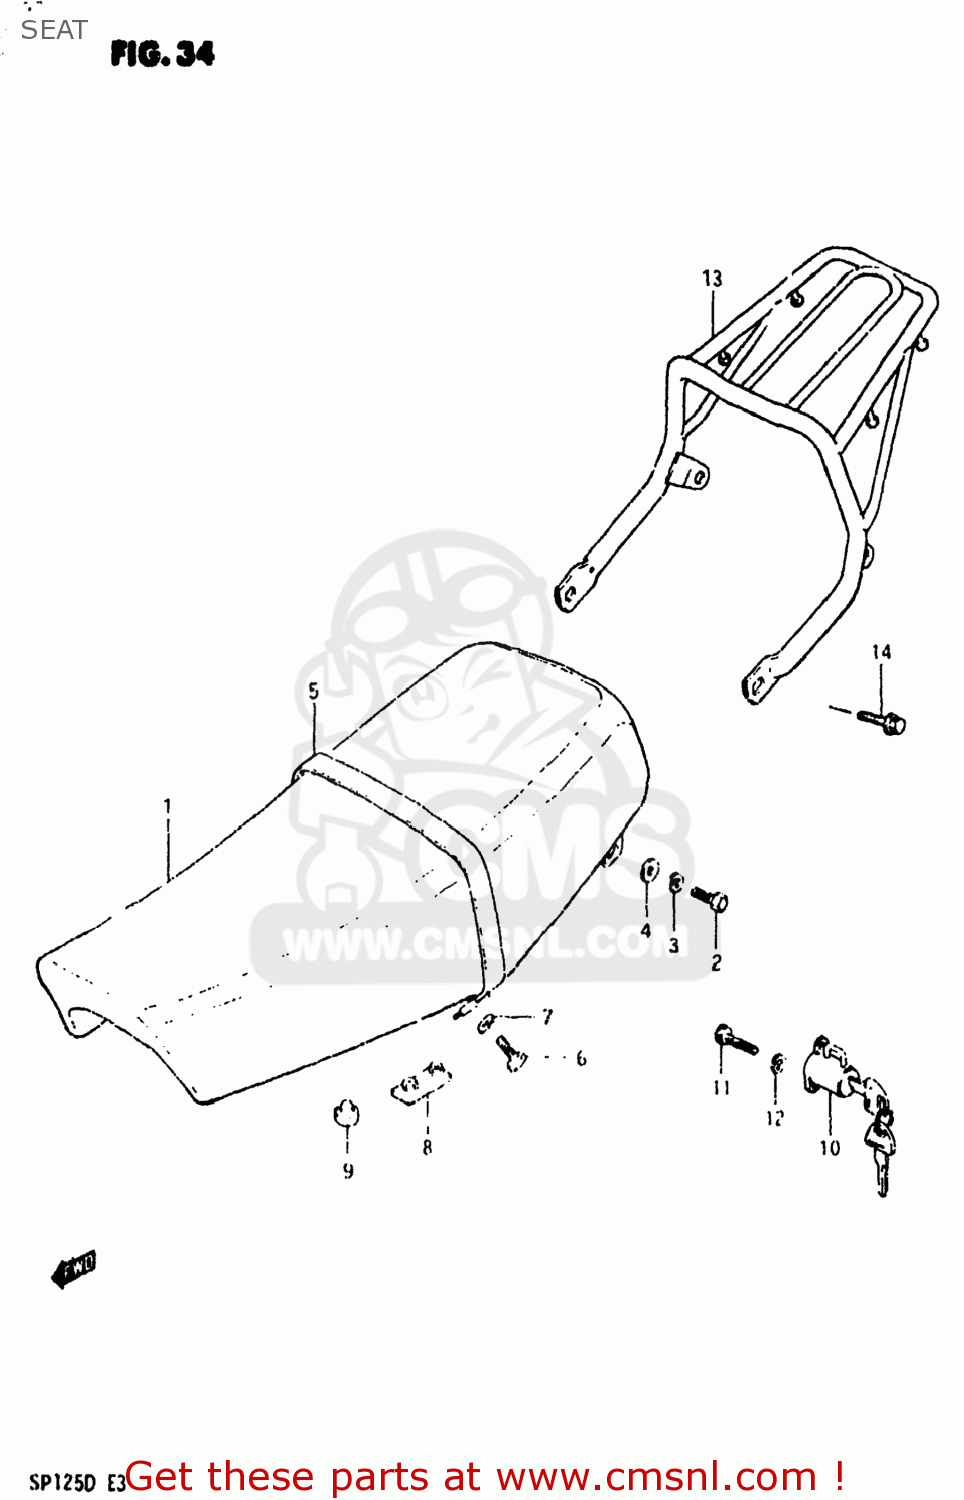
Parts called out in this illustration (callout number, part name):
1	SEAT ASSEMBLY
2	BOLT
3	LOCK WASHER
4	WASHER
5	BAND,SEAT
6	BOLT
7	LOCK WASHER
8	CUSHION
9	CUSHION
10	LOCK ASSEMBLY,HELMET
11	BOLT 6X11
12	LOCK WASHER
13	CARRIER
14	BOLT
